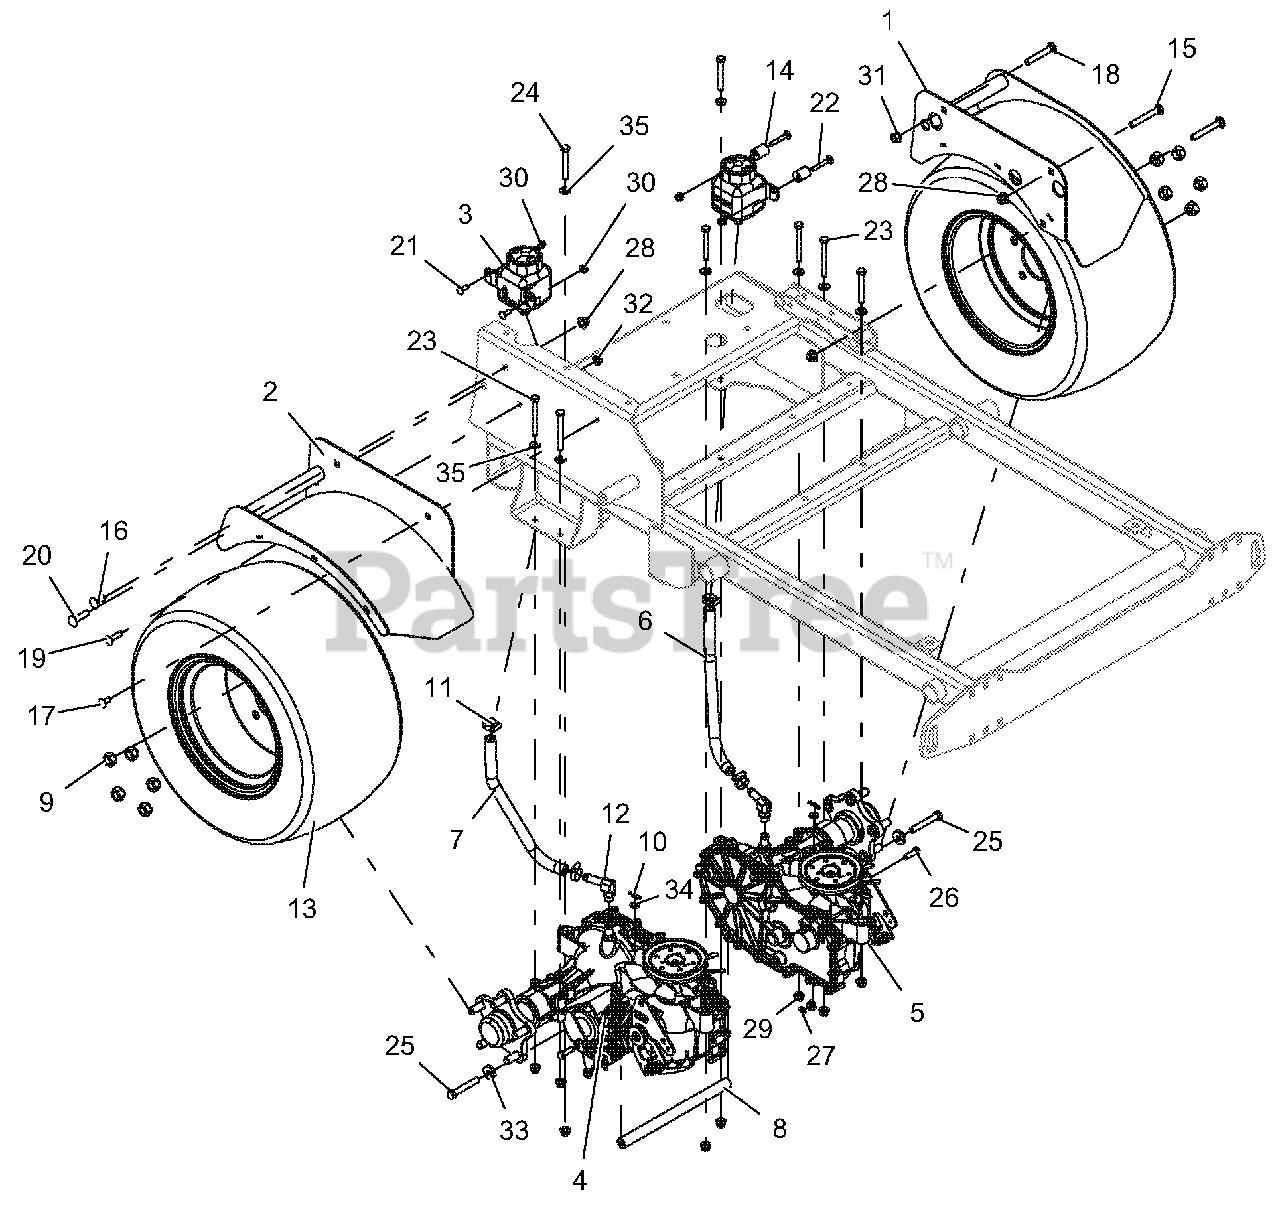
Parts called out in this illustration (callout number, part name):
1	WLDMT, LH FENDER - RED
2	WLDMT, RH FENDER - RED
3	TANK, EXPANSION ZT2800
4	TRANSAXLE, 3400, PRO-STANCE, RH
5	TRANSAXLE, 3400, PRO-STANCE, LH
6	HOSE, HYD OVERFLOW
7	HOSE, HYD OVERFLOW
8	SHAFT, CROSS BRACE
9	NUT, LUG .500-13
10	PIN-HAIR, ENDRIES #25 YWZC
11	CLAMP, .88 DIA HOSE
12	FITTING, HYD (90 DEG)
13	ASSM TIREWHEEL, 20 x 10.50 x .8
14	ECCENTRIC
15	BLT-RDHDSQNK .38-16 x 2.75 G5 Y
16	BLT-RDHDSQNK .38-16 x 1.00 G5 YWZC
17	BLT-RDHDSQNK .31-18 x .75 G5 YWZC
18	BLT-RDHDSQNK .38-16 x 2.50 G5 Y
19	BLT-RDHDSQNK .31-18 x 1.25 G5 Y
20	BLT-RDHDSQNK .38-16 x 1.50 G5 Y
21	BLT-RDHDSQNK .25-20 x .75 G5 YWZC
22	BLT-RDHDSQNK .25-20 x 1.75 G5
23	BLT-HEX .31-18 x 3.00 GR5 YWZC
24	BLT-HEX .31-18 x 2.50 GR5 YWZC
25	BLT-HEX .38-16 x 2.50 GR5 YWZC
26	BLT-HEX .31-18 x 1.00 GR5 YWZC
27	@NUT-LK-CTR-JAM .31-18 YWZC
28	NUT-LK-NYL-FLG .38-16 YWZC
29	NUT-LK-NYL-FLG .31-18 YWZC
30	NUT-LK-NYL-FLG .25-20 YWZC
31	NUT, LK-TOP-FLG .38-16 YWZC
32	@NUT-SPNLK-FLG .312-18 YWZC
33	WSHR-FL-STL .406 x 1.00 x .188 YWZC
34	WSHR-FL-STL .281 x .62 x .065 YWZC
35	WSHR-FL-STL .312 x .734 x .065 YWZ
